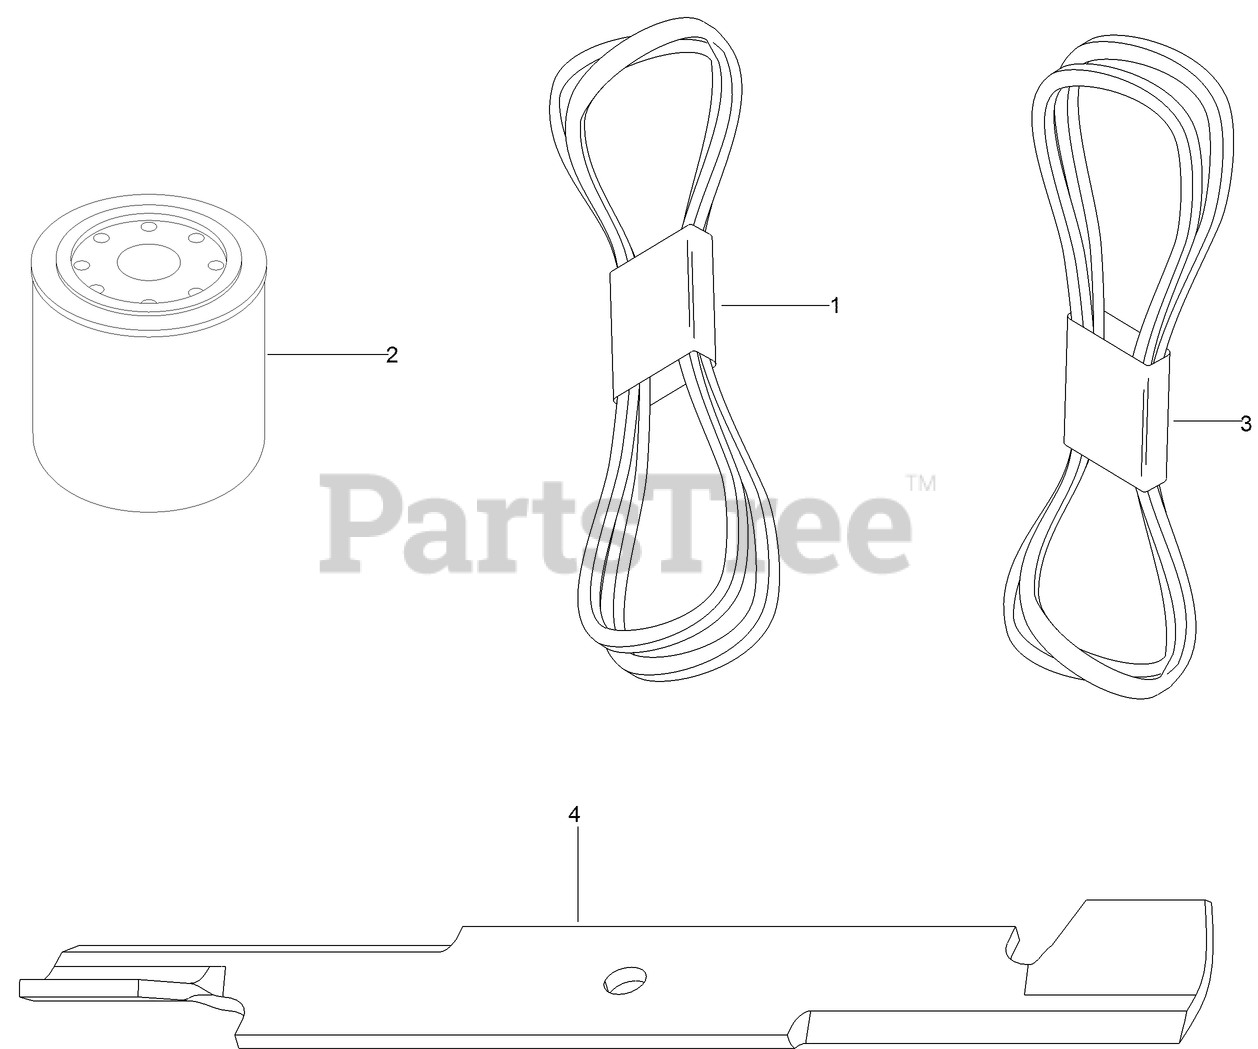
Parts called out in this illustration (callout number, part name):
1	BELT-V
2	CARTRIDGE-FILTER, OIL
3	BELT-V
4	BLADE-18IN, HI FLOW
